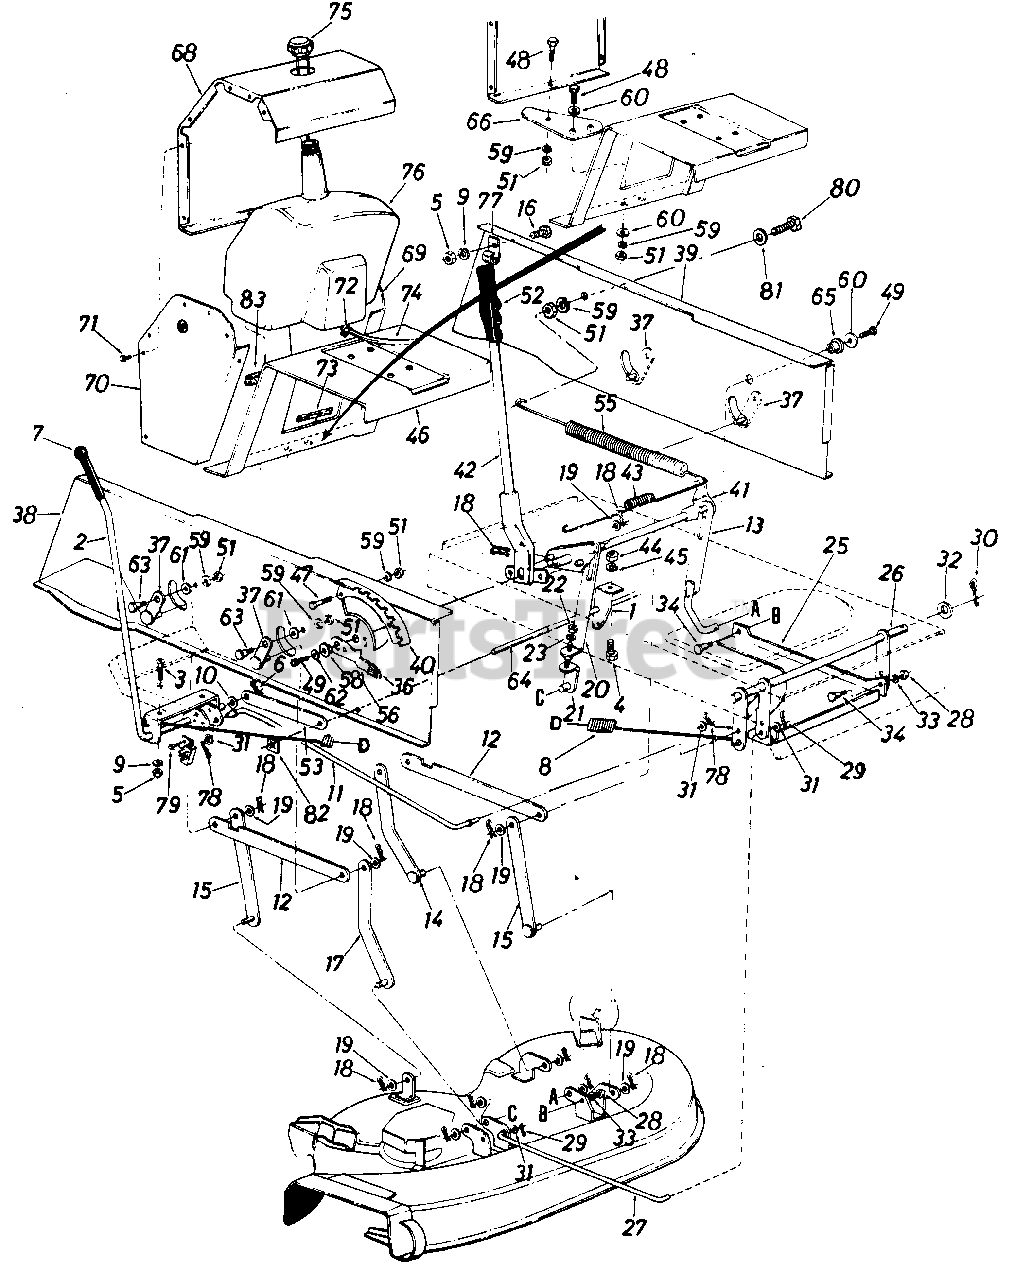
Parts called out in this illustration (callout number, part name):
1	Spring Hanger Bracket
2	Deck Engagement Lever Ass'y.
3	Truss Mach. Scr. 5/16-18 x .75" Lg.
4	Hex Bolt 1/4-20 X .62" Lg.
5	Hex Nut 5/16-18 Thd.
6	Cotter Pin 3/32" Dia. x 1.00" Lg.
8	Ext Spring .99" O.D. x 22" Lg.
9	L-Wash. 5/16" I.D.
10	Fl-Wash. .510" I.D. x 1.0" O.D.
11	Drive Deck Control Rod
12	Connecting Rod 3/16 x 1 x 1 2.5
13	Deck Lift Link Ass'y.
14	Deck Hanger Link Ass'y. Rear L.H.
15	Deck Hanger Link Ass'y.
16	Hex Bolt 5/16-18 x .75" Lg.
17	Deck Hanger Link Ass'y. Front R.H.
18	Inter. Cotter Pin 1/2" Dia.
19	Fl-Wash. .531 I.D. x .93" 0. D.
20	Adj. Link Deck Lifting
21	Adj. Lower Link Ass'y.
22	Hex Jam Nut 3/8-24 Thd.
23	L-Wash. 3/8" I.D.
25	Diagonal Brace
26	Stabilizer Shaft Ass'y.
27	Stabilizer Rod
28	Hex Nut 3/8-16 Thd.
29	Cotter Pin 3/32" Dia. x 1.0" Lg.
30	Cotter Pin 1/8" Dia. x 1.25" Lg.
31	Fl-Wash. .385" I.D. x .620" O.D.
32	Fl-Wash. .635" I.D. x 1.12" O.D.
33	L-Wash. 3/8" I.D.
34	Shoulder Bolt 3/8-16
36	Knob Height Adj.
37	Pivot Link Ass'y.
38	Side Panel Upper Frame R.H.
39	Side Panel Upper Frame L.H.
40	Index Brkt.
41	Lift Shaft Ass'y.
42	Lift Handle Brkt. Ass'y.
43	Ext. Spring .56" I.D. x 32 Coils
44	Hex Nut 1/4-20 Thd.
45	L-Wash. 1/4" I.D.
46	Hitch Plate
47	Hex Bolt 5/16-18 x .75" Lg.
48	Hex Bolt 5/16-18 x 1.00" Lg. (Grade 5)
49	Hex Wash. TT-Tap Scr. 5/16-18 x .62" Lg.
51	Hex Nut 5/16-18 Thd.
52	Grip
53	Link 1.0" x 7.5" x .19
55	Ext. Spring .99" Dia. x 11.00" Lg.
56	Deck Lift Down Stop
58	Flange Brg. .630" I.D.
59	L-Wash. 5/16" I.D.
60	Fl-Wash. .344" I.D. x 1.125" O.D. x .125
61	Fl-Wash. .344" I.D. x .62" O.D. x .063
62	Fl-Wash. .344" I.D. x 1.125 O.D.
63	Shld. Bolt .437" Dia. x .180
64	Running Board Rod
65	Flange Brg. .632" I.D.
66	Hitch Bar
68	Gas Tank Housing Main Panel
69	Side Panel L.H. Gas Tank
70	Side Panel R.H. Gas Tank
71	Truss Mach. B-Tapp Scr. #10 x .50" Lg.
72	Hose Clamp .406" Dia.
73	Trim Strip 5" Lg.
74	Gas Line 44" Lg.
75	Gas Tank Cap
76	Gas Tank
77	Hose Clamp
78	Cotter Pin 3/32" Dia. x .75" Lg.
79	Hex Wash. Hd. Tap Scr. 1/4 x.50" Lg.
80	Hex Bolt 5/16-18 x 1.50" Lg.
81	Fl-Wash. .344" I.D. x .875" 0. D.
82	Speed Nut for .500" Dia. Stud
83	Foam Strip 3/8" x 1-1/8" x 11/2 Lg.
